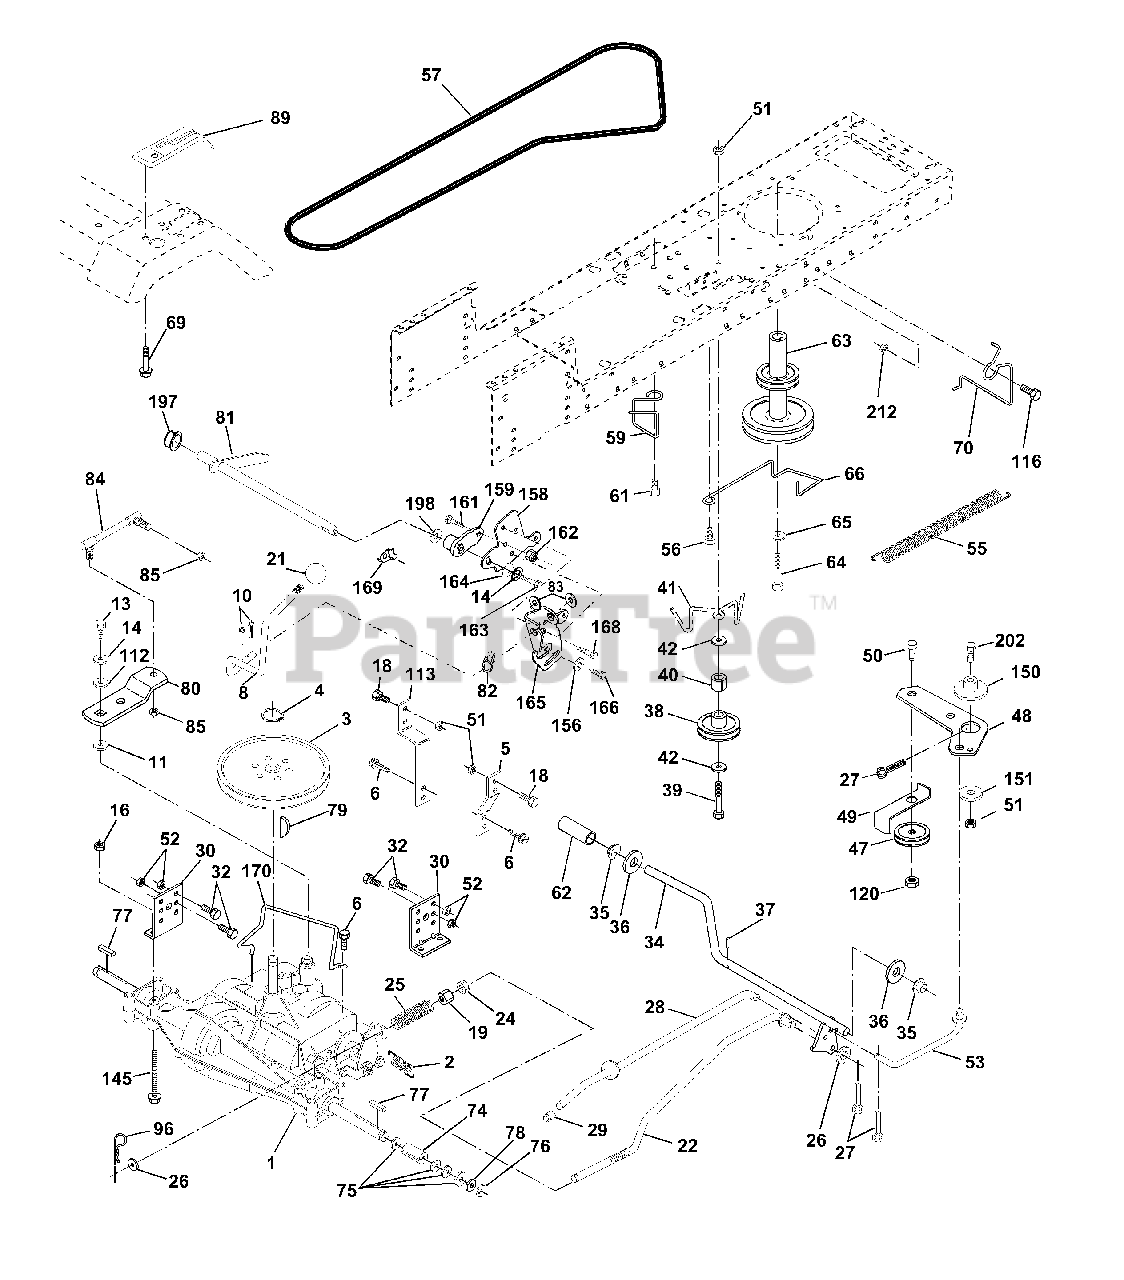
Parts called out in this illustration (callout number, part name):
2	Spring Return Brake T/a Zinc
3	Pulley Transaxle 18" tires
4	Ring Retainer # 5100-62
5	Strap Torque 30 Degrees
6	Screw 5/16-18 X 3/4
8	Rod Shift Fender Adjust Lt
10	Pin Cotter 1/8 X 1 Cad
11	Washer Plate Shf 388 Sq Hole
13	Bolt 1/4-28 Unf Gr 8 W/Patch
14	Washer Lock Hvy Helical
16	Nut Lock Hex w/ins 5/16-18
18	Bolt, Fin Hex 3/8-16 UNC x 1 Gr. 5
19	Nut Lock 3/8-16 Unc
21	Knob
22	Rod Brake Blk Zinc 26 840
24	Nut Hex Jam 3/8-16 Unc
25	Spring Rod Brake 2 00 Zinc
26	Washer 13/32 X 13/16 X 16 Ga
27	Pin Cotter 1/8 X 3/4 Cad
28	Rod Brake Parking LT/YT
29	Cap Brake Parking
30	Bracket Mtg Transaxle
32	Bolt Hex Hd 5/16-18unc X 3/4
34	Shaft Asm Pedal Foot
35	Bearing Nylon Blk 629 Id
36	Washer 21/32 X 1 X 16 Ga
37	Pin Roll 3/16 X 1"
38	Pulley Composite Flat
39	Bolt Fin Hex 3/8-16 unc X 3
40	Spacer Split Steel
41	Keeper Belt Flat Idler
42	Washer 13/32 X 13/16 X 12 Ga
47	Pulley Idler V Groove Plastic
48	Bellcrank Asm
49	Retainer Belt Style Spring
50	Bolt Hex Hd 3/8-16unc X 1-1/2
51	Nut Crownlock 3/8-16 Unc
52	Nut Crownlock 5/16-18 Unc
53	Link Clutch
55	Spring Return Clutch 6 75
56	Screw 3/8-16 x 1
57	V-Belt Ground Drive 95 25
59	Keeper Belt Span Ctr
61	Screw 3/8-16x.75
62	Cover Pedal Blk Round
63	Engine Pulley
64	Bolt Hex
65	Washer Lock Hvy Hlcl Spr 7/16
66	Keeper Belt Engine Foolproof
69	Screw Hex wsh Hi Lo 1/4 x 1/2 unc
70	Guide Belt Mower Drive RH
74	Spacer Axle
75	Washer 25/32 X 1 1/4 X 16 Ga
76	E-ring #5133-75
77	Key Square 2 0 X 1845/ 1865
78	Washer 25/32 X 1-5/8 X 16 Ga
79	Key Woodruff #9 3/16 x 3/4
80	Arm Shift
81	Shaft Asm Cross Tapered PMST/20
82	Spring Torsion T/a
83	Washer 17/32 X 3/4 X 16 Ga
84	Link Transaxle PMST/20" Zinc
85	Nut Lock Center 1/4 - 28 FNTHD
89	Console Shift STLT
96	Retainer Spring 1"
112	Washer 9/32 x 3/4 x 10 Ga.
113	Strap Torque LT
116	Bolt RDHD SQNK 3/8-16 Unc x 1
120	Nut Lock Fkg. 3/8-16 UNC
145	Bolt Hex FLGHD 5/16-18 Gr. 5
150	Spacer Retainer
151	Washer 13/32 x 2 x 10
156	Washer Srrted 5/16ID x 1.125
158	Bracket Shift Mount
159	Hub Tapered Flange Shift Lt
161	Bolt Rdhd Sqnk 1/4-20 x 3/4 Gr
162	Nut Crownlock 1/4-20 Unc
163	Bolt Hex Fin 1/4-20 Unc x 1 Gr 5
164	Washer 5/8 x .281 x 10 Ga
165	Bracket Pivot Lever
166	Screw 5/16-18 x 5/8
168	Bolt Shoulder 5/16-18 x .561
169	Plate Fastening
170	Keeper Belt Transaxle Gear
197	Nyliner Snap-In
198	Washer Nyliner
202	Bolt Carr Sh 3/8-16 x 1-1/2 Gr. 5
212	Nut Hex Flange Lock
